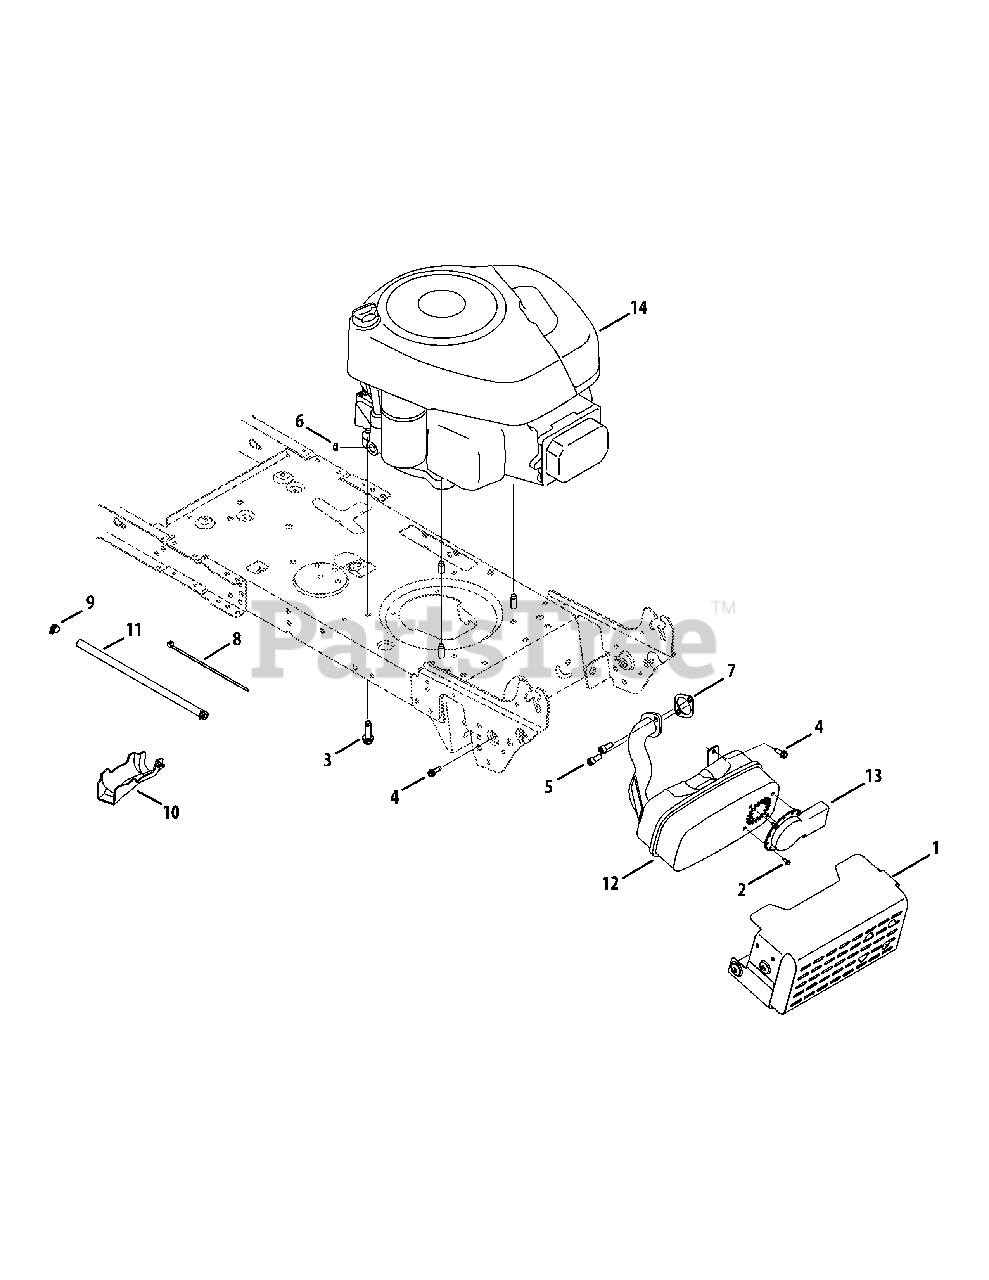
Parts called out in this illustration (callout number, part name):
1	Muffler Shield Assembly
2	Screw, AB #8-18 0.500
3	Tap Screw, 3/8-16 1.000
4	Tap Screw, 1/4-20 0.750
5	Screw, Socket Head, 5/16-18 x .750
6	Sems Nut, 1/4-20
7	Exhaust Gasket
8	Cable Tie, 3/16 X .05 X 7.4
9	Hose Clamp, .490 Dia.
10	Oil Drain Sleeve
11	Low Permeation Fuel Hose, 1/4
12	Briggs Single Muffler
13	Long Muffler Deflector
14	Replacement Engine 331877-0869-G5
